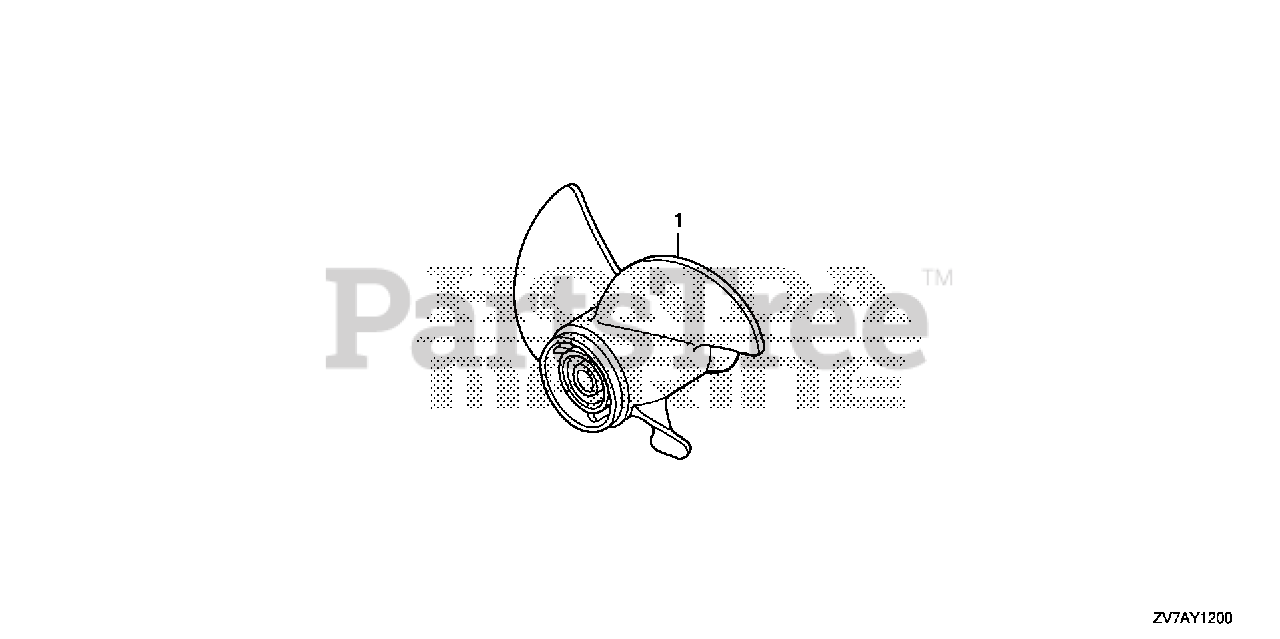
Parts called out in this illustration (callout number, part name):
1	PROPELLER, THREE-BLADE (9-3/4X9-7/8) *NH283* (STIN GRAY)
1	PROPELLER, THREE-BLADE (10X8-1/4) *NH283* (STIN GRAY)
1	PROPELLER, THREE-BLADE (9-7/8X12) *NH283* (STIN GRAY)
1	PROPELLER, THREE-BLADE (9-7/8X9) *NH283* (STIN GRAY)
1	PROPELLER, THREE-BLADE (9-7/8X10) *NH283* (STIN GRAY)
1	PROPELLER, THREE-BLADE (9-7/8X11) *NH283* (STIN GRAY)
1	PROPELLER, THREE-BLADE (9-7/8X13) *NH283* (STIN GRAY)
